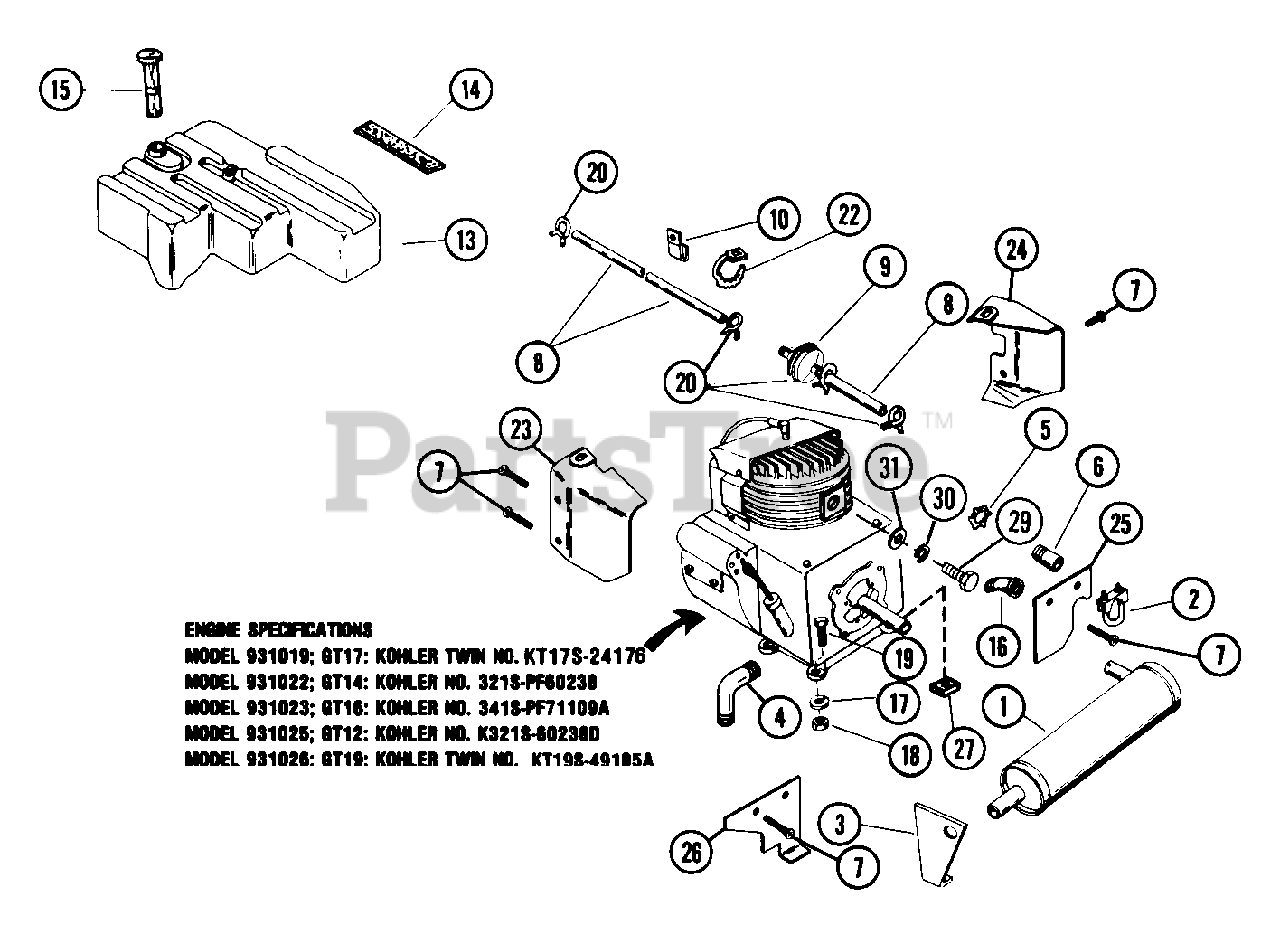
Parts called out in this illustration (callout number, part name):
1	MUFFLER-TWIN EXHAUST
1	MUFFLER
2	EXHAUST CLAMP
2	EXHAUST CLAMP 1 3/8
3	BALL JOINT R.H.
3	MUFFLER BRACKET
4	STREET ELBOW
5	NUT-LK CONDUIT 1.00
5	NUT-LK CONDUIT 1.25
6	PIPE
6	ADAPTER
7	SCR-TAP 12-14X.62 HWH PL B
8	HOSE (SERV. ONLY)
9	FUEL FILTER
10	J-CLAMP
13	GAS TANK ASSEMBLY
13	GAS TANK
14	1/4 X 3/4 X 1 IN FOAM TAPE
15	GAS GAUGE & CAP
16	STREET ELBOW 1-1/4 X 45 DEGREE
16	45 DEG ELBOW
17	WSHR-LK .375X.094 MED PL
18	NUT-LK TOP .375-16 GR C YWZC
19	BLT-HEX .38-16X1.50 PL GR5
20	CLAMP-HOSE WIR.490/.510X.092#8
22	TIE DOWN
23	R.H. CYLINDER BAFFLE
24	L.H. CYLINDER BAFFLE
25	L.H. BAFFLE
26	R.H. BAFFLE
27	NUT-SPECIAL-HDND .38-16 GR5 PL
28	WSHR-FL-STL .38X.875X.083 PL
29	STUD
29	ENGINE STUD
30	WSHR-LK .250X.077 HVY PL
30	WSHR-LK .312X.097 PL HVY
31	WSHR-FL-STL.312X.734X.065PL
31	WSHR-FL-STL .250X.562X.049 PL
